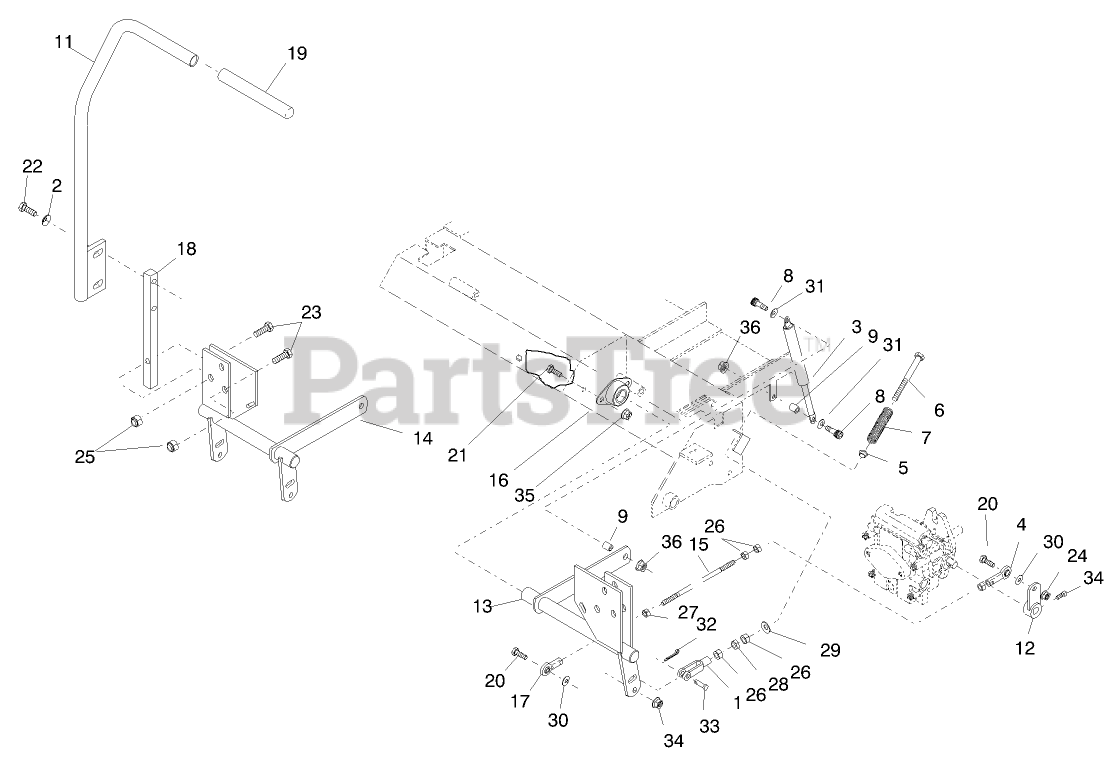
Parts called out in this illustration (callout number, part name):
1	Yoke
2	Washer
3	Damper
4	Ball Joint
5	Bushing
6	Bolt
7	Spring
8	Screw-HSH
9	Spacer
10	Lever-LH
11	Lever-RH
12	Arm-Pump Control
13	Bracket-Motion Control LH
14	Bracket-Motion Control RH
15	Linkage
16	Bearing-Side Flange
17	Ball Joint LH
18	Arm
19	Grip
20	SCREW-HH
21	SCREW-HH
22	SCREW-HH
23	SCREW-HH
24	Screw
25	NUT-HEX
26	NUT-HEX
27	Nut
28	NUT-JAM
29	WASHER-FLAT
30	WASHER-FLAT
31	WASHER-PLAIN
32	PIN-COTTER
33	Pin-Clevis
34	NUT-HF
35	NUT-FLANGE
36	NUT-HF
